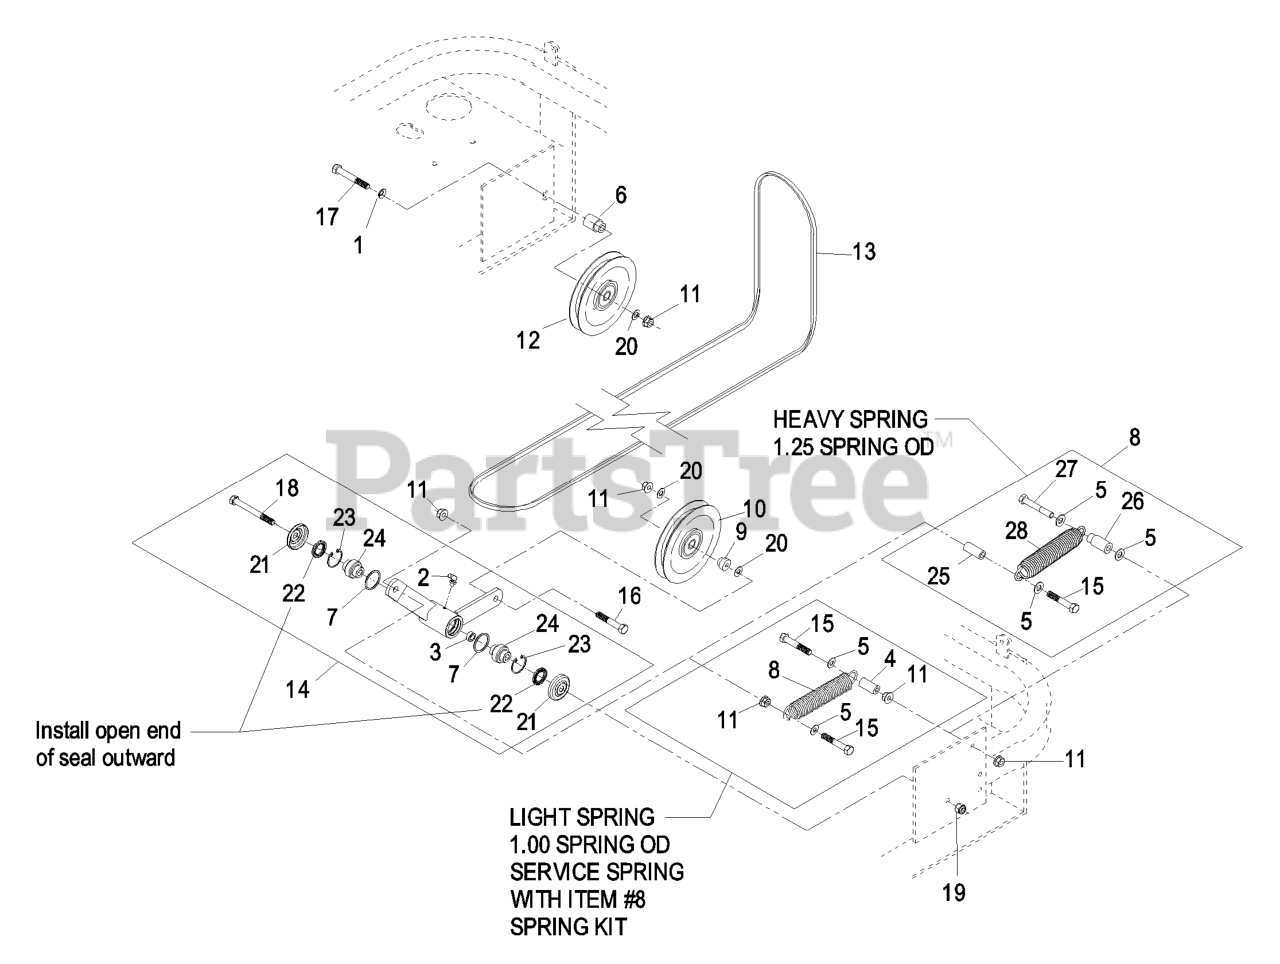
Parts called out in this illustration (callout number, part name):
1	WASHER-BELLEVILLE
2	FITTING-GREASE, 90 DEG
5	WASHER-FLAT
6	BUSHING-IDLER
9	BUSHING-IDLER
10	PULLEY-IDLER
11	NUT-HHF, WHIZ
12	PULLEY-IDLER
13	BELT,B 116.1"
14	KIT,MULE IDLER LZ
15	SCREW-HH
16	SCREW-HH
17	SCREW-HH
18	SCREW-HH
19	NUT-LOCK, NI
20	WASHER-FLAT
21	GUARD-TOP
22	SEAL-LIP, SINGLE
23	RING-SNAP
24	BEARING-SPHERICAL
25	BUSHING-LEVER, LIFT
27	BOLT-CARR
